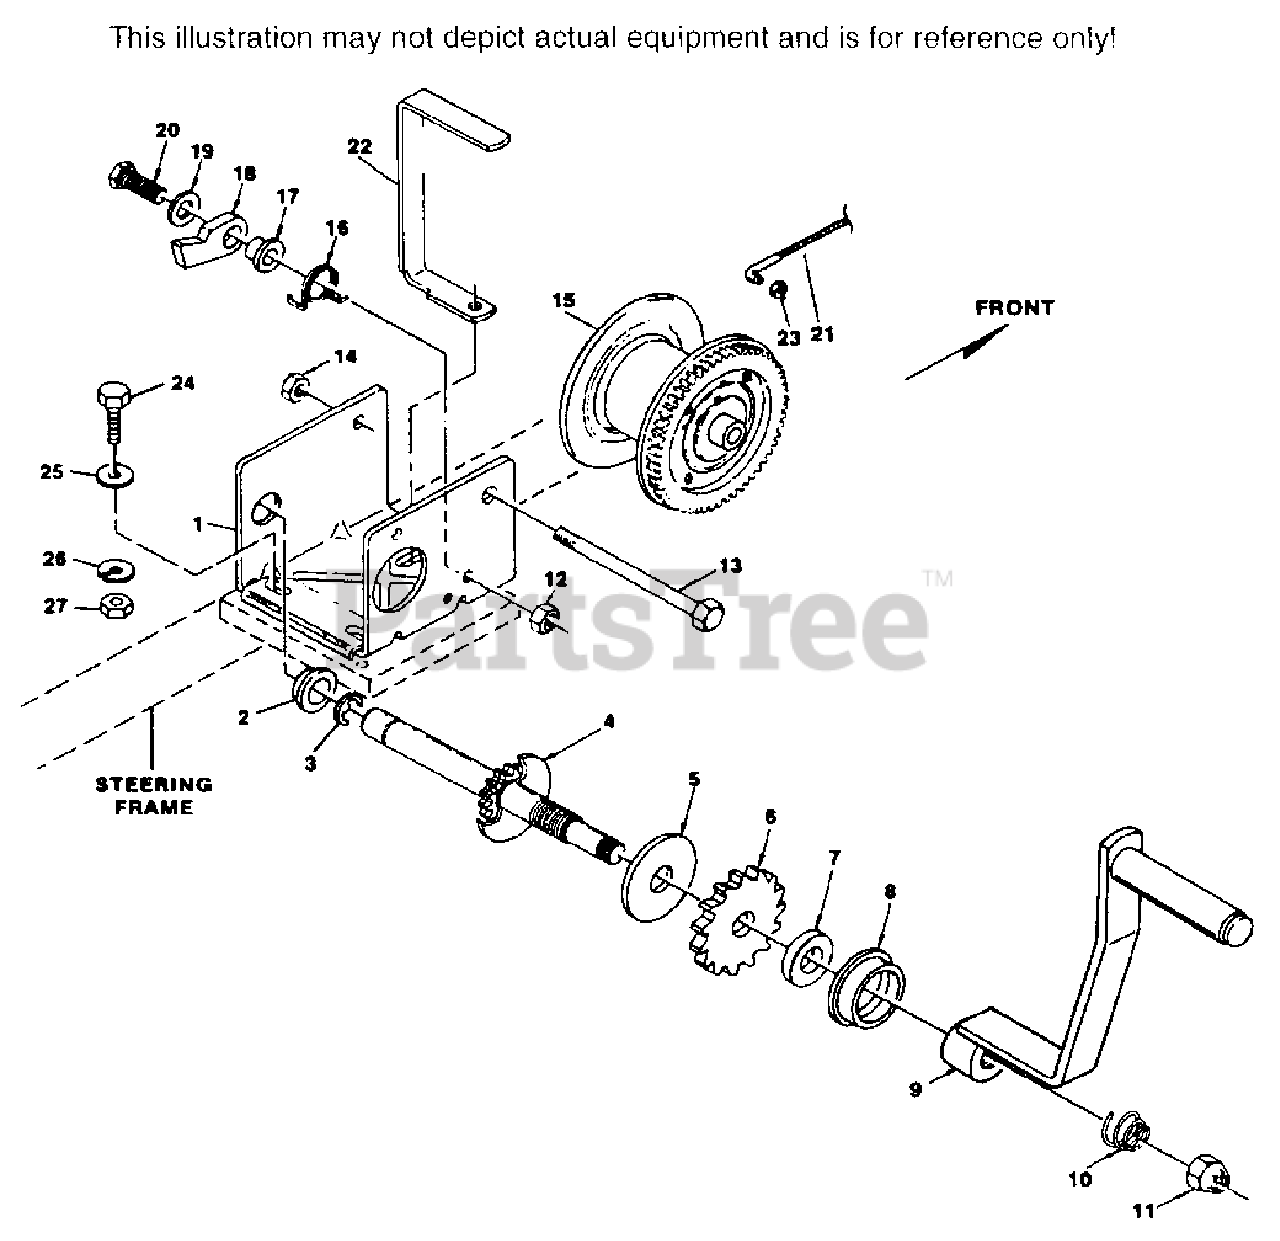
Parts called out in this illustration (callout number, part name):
1	WINCH ASSEMBLY(INCL. 1-8, 10-20)
2	SHAFT BUSHING
3	E-RING
4	DRIVE SHAFT
5	PRESSURE PLATE
6	RATCHET WHEEL
7	PRESSURE WASHER
8	SHAFT BUSHING
9	WINCH HANDLE
10	HANDLE SPRING
11	HANDLE NUT
12	HEX LOCKNUT, 3/8-16
13	REEL SHAFT
14	LOCK NUT, 7/16-14
15	WINCH REEL
16	RATCHET SPRING
17	RATCHET SPACER
18	RATCHET PAWL
19	FLAT WASHER
20	RATCHET BOLT
21	WINCH CABLE ASSEMBLY
22	CABLE GUIDE
23	HEX LOCK NUT, 1/4-28
26	LOCK WASHER, 3/8 SPRING
